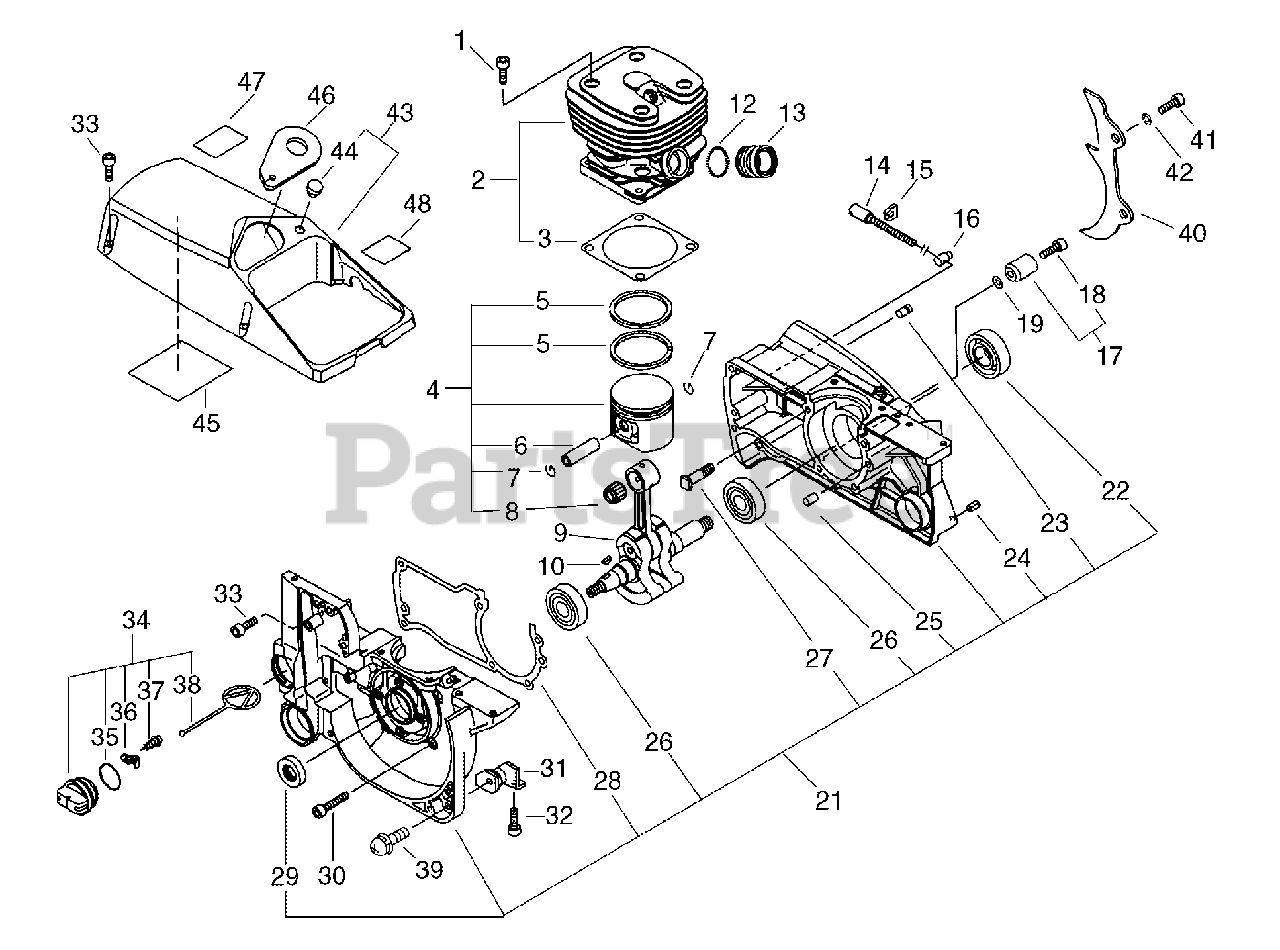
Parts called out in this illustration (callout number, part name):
1	BOLT 6×25
2	CYLINDER ASSY
3	GASKET, CYLINDER
4	PISTON KIT
5	RING, PISTON
6	PIN, PISTON
7	RING, RETAINING
8	BEARING, NEEDLE
9	CRANKSHAFT
10	KEY, WOODRUFF
13	ADAPTOR, INTAKE
14	SCREW, ADJUSTER
16	TENSIONER, CHAIN
17	CHAIN CATCHER KIT
18	BOLT 5×20
19	WASHER, FLAT 5.5×10×0.8
21	CRANKCASE KIT
22	SEAL, OIL
23	VENT ASSY
24	PIN, SPRING 5×10
25	PIN, LOCATING 5×10
26	BEARING, BALL 6203 C3
27	STUD, GUIDE BAR 8
28	GASKET, CRANKCASE
29	SEAL, OIL
30	BOLT M5×35
32	BOLT 5×14
33	BOLT 5×20
34	CAP ASSY, OIL
35	O-RING 25
36	RETAINER, CONNECTOR
37	SCREW, TAPPING 3×8
38	CONNECTOR, CAP L= 60 MM
39	SCREW 5×14
40	SPIKE, BUMPER
41	BOLT 6×20
42	WASHER, SPRING 6
43	ENGINE COVER KIT - ORANGE
46	PLATE, GUIDE
47	LABEL, CAUTION
48	LABEL, CAUTION
